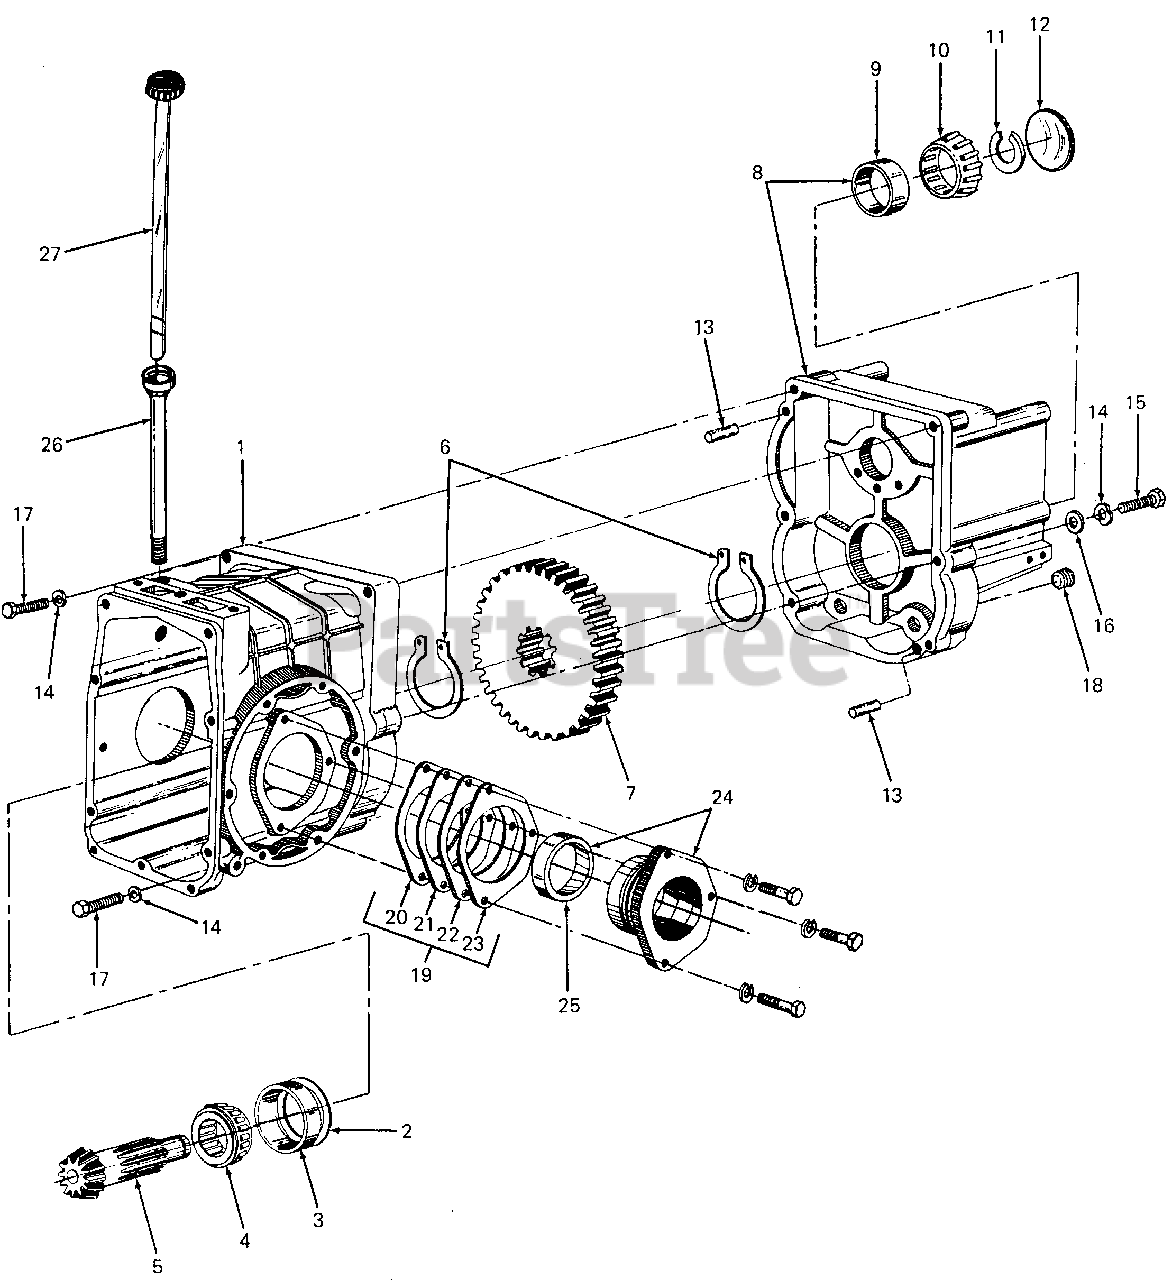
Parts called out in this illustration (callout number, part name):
1	Housing Assy, Rear Transaxle
2	Shim, Rear Bearing Cup, .004 Thk
3	Cup, Roller Bearing
4	Cone, Roller Bearing
5	Shaft, Bevel Pinion
6	Ring, Retaining, 1.312 Dia
7	Gear, Reduction - 68T
8	Housing Assy, Adapter w/Cup
9	Cup, Roller Bearing
10	Cone, Roller Bearing
11	Retainer, Front Bearing, .125 Thk
12	Plug, Expansion, 2.12 OD
13	Pin, Dowel, 3/8 Dia X 5/8 Lg
14	Washer, Spring, .445 X .75 X .017 Thk
15	Screw, Hex Cap, 7/16-14 X 2.5 Lg GR5
16	Washer, Flat, .46 X .875 X .060 Thk
17	Screw, Hex Cap, 7/16-14 X 1.75 Lg GR5
18	Plug, Drain
19	Shim Package
20	Shim, Bearing Retainer, .004 Thk
21	Shim, Bearing Retainer, .007 Thk
22	Shim, Bearing Retainer, .014 Thk
23	Shim, Bearing Retainer, .028 Thk
24	Retainer Assy, Bearing w/Cup
25	Cup, Roller Bearing
26	Tube, Dipstick
27	Blade Assy, Dipstick
